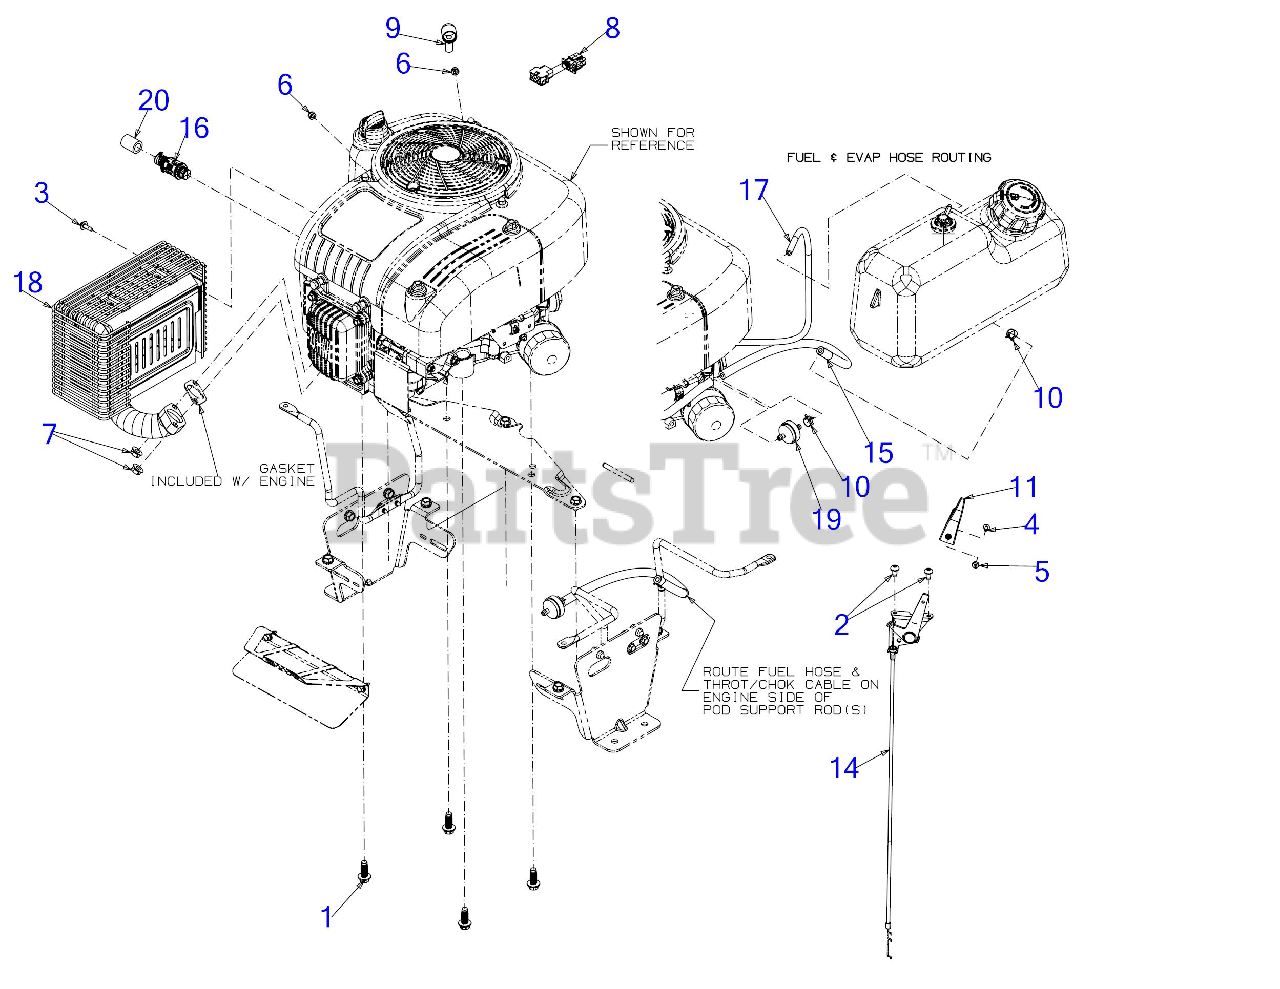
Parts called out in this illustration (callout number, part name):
1	SCREW 3/8-16 x 1
2	SCREW 1/4-20 x .5
3	SCREW M6-1 x .625
4	SCREW #8-32X.38 LG
5	HEX NUT 8-32
6	HEX NUT
7	HEX FLANGE NUT M8X
8	JUMPER HARNESS
9	TERMINAL COVER BLACK
10	HOSE CLAMP 1/20
11	THROTTLE CONTROL KNOB
14	THROTTLE/CHOKE CABLE 19.0
15	FUEL HOSE LOW PERMEATION
16	OIL DRAIN VALVE
17	VENT HOSE 3/16 ID
18	MUFFLER ASSEMBLY
19	FUEL FILTER
20	DRAIN HOSE 14''
